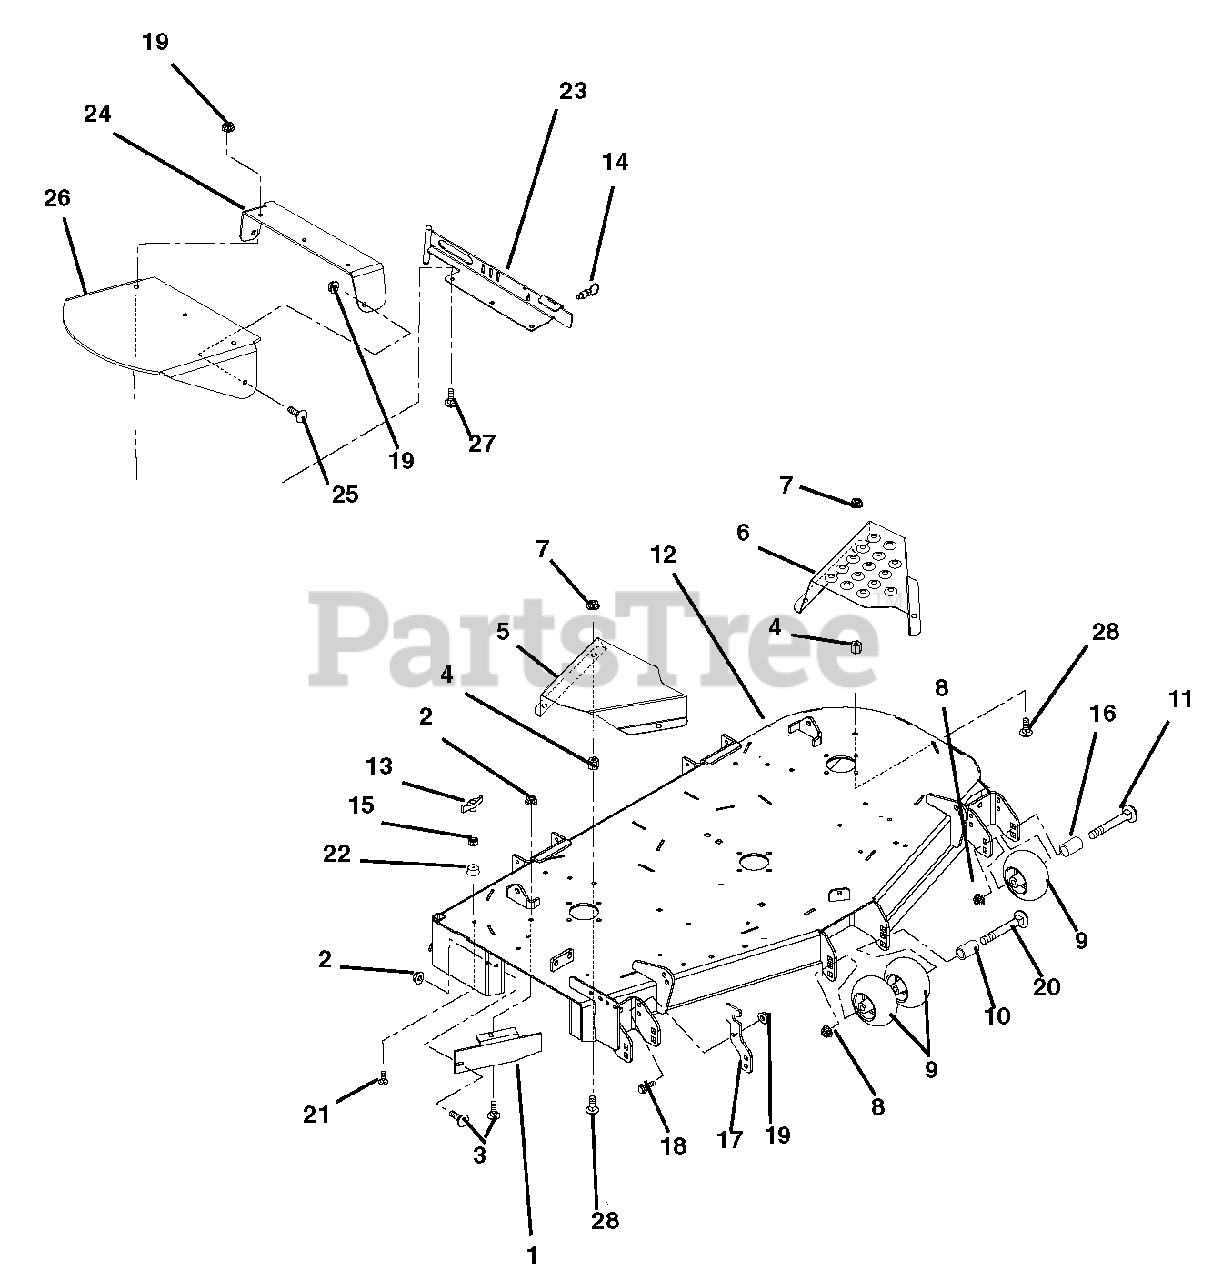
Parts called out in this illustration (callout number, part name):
1	60-in. Discharge Baffle (195)
2	Nut, .31-18 Nyloc Flange
3	Bolt, Round Head Square Neck .31-18 x 1.00 Grade 5
4	Nut, Heavy Hex .38-16
5	60/66-in. Right Hand Spindle Guard (195)
6	60-in. Left Hand Spindle Guard (195)
7	Nut, Spin Lock-Flange .375-16
8	Nut .50-13 Nyloc Flange
9	Anti-Scalp Wheel
11	Bolt-Round Head Square Neck .50-13 x 5.00
12	60-in. Mower Deck (195)
13	Knob, Clamping, .312-18 Nyloc
14	Pin, Pull Plunger .50-13 Thread x .310
15	Nut, Locking Center .31-18
16	Spacer, .510 x .625 x 3.35
17	Chute, Storage Bracket
18	Bolt, Hex .38-16 x 1.00 Grade 5
19	Nut, .38-16 Nyloc Flange
20	Bolt, Round Head Square Neck .50-13 x 8.50
21	Bolt, Round Head Square Neck .31-18 x 1.50
22	Bumper, Recessed 1.50 x .63 , .31 Thru Hole
23	60-inch Discharge Chute Mounting Weldment (195)
24	Rubber Discharge Chute Support
25	Bolt, Round Head Square Neck .38-16 x 1.00 Grade 5
26	Chute, Rubber Discharge
27	Bolt, Round Head Square Neck .38-16 x 1.25 Grade 5
28	Bolt, Hex .38-16 x 1.25 Grade 5
